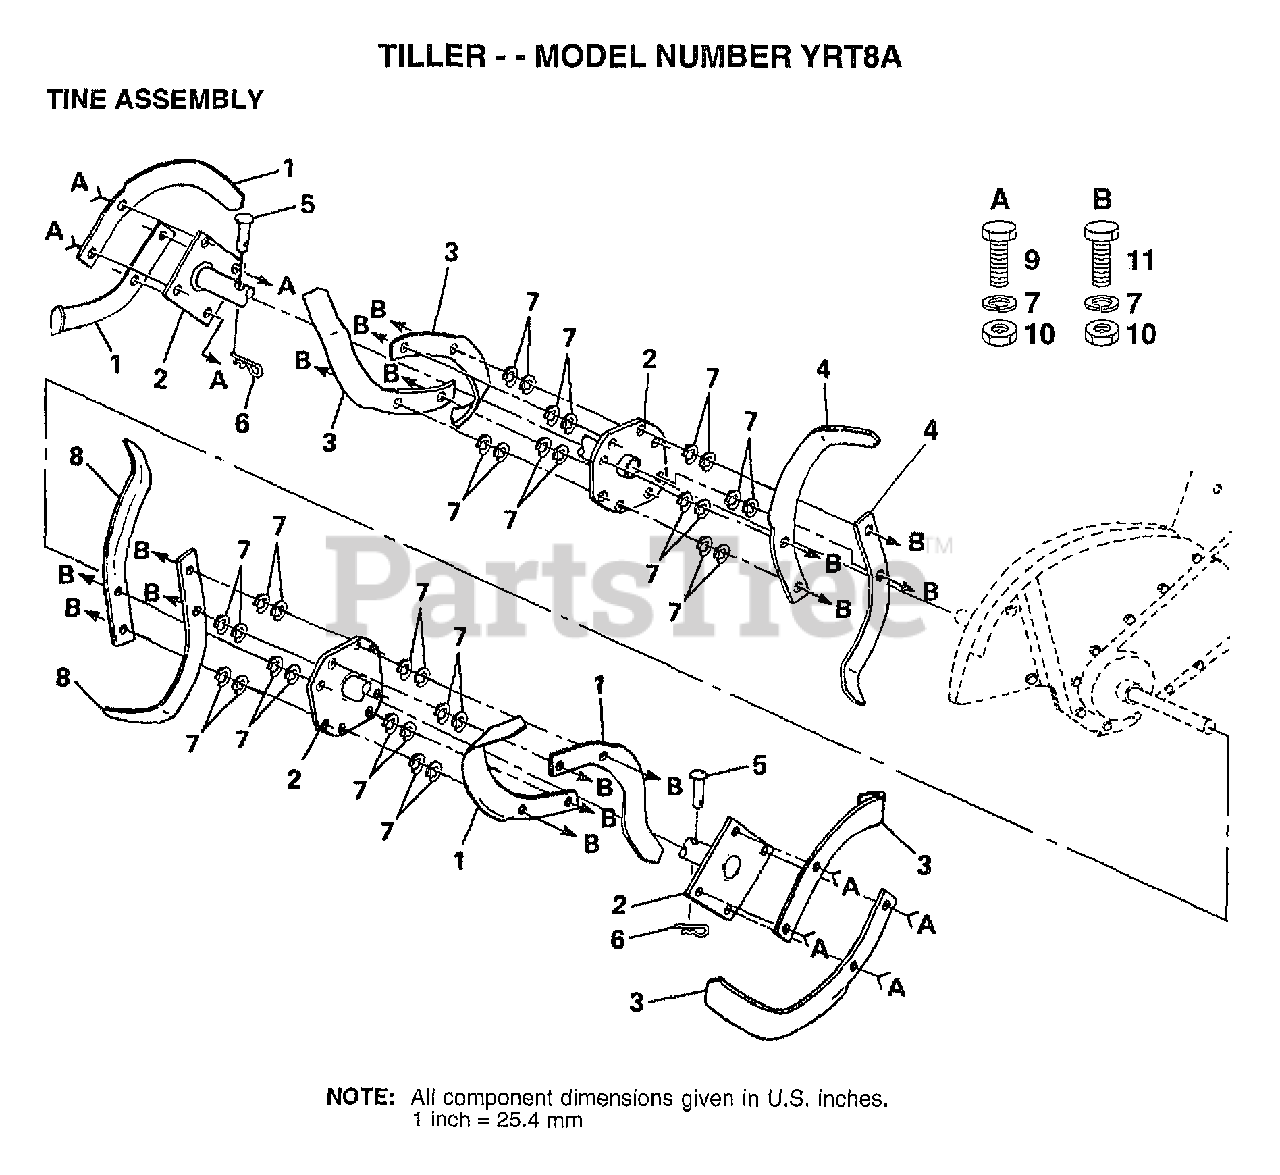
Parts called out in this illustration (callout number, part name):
2	TINE ASSY CRT
4	TINE.LH.CRT
5	RIVET.PAN HD.1.75
6	RETAINER.SPRING
7	LOCKWASHER
8	TINE RH CRT
9	BOLT
11	BOLT.3/8-24X1-1/2
